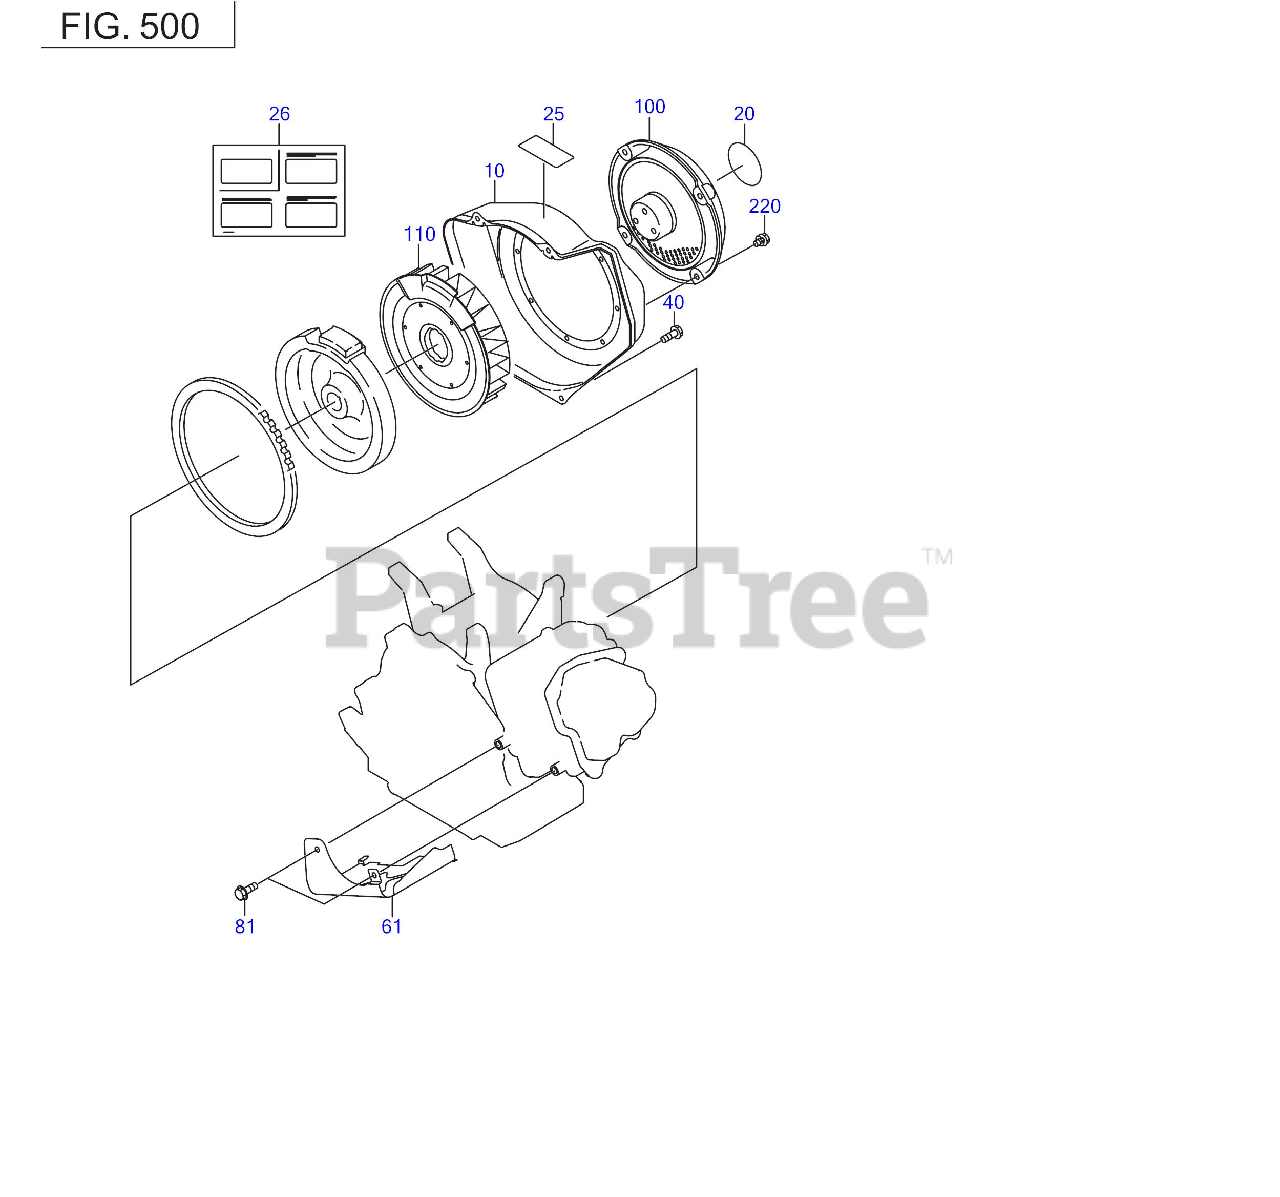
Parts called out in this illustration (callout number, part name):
10	BLOWER HOUSING CP
20	LABEL(TRADE MARK)
25	LABEL(WARNING)
26	LABEL(WARNING)
61	BAFFLE 2(HEAD)
100	STARTER CASE AY
110	COOLING BLOWER
220	BOLT AND WASHER AY
